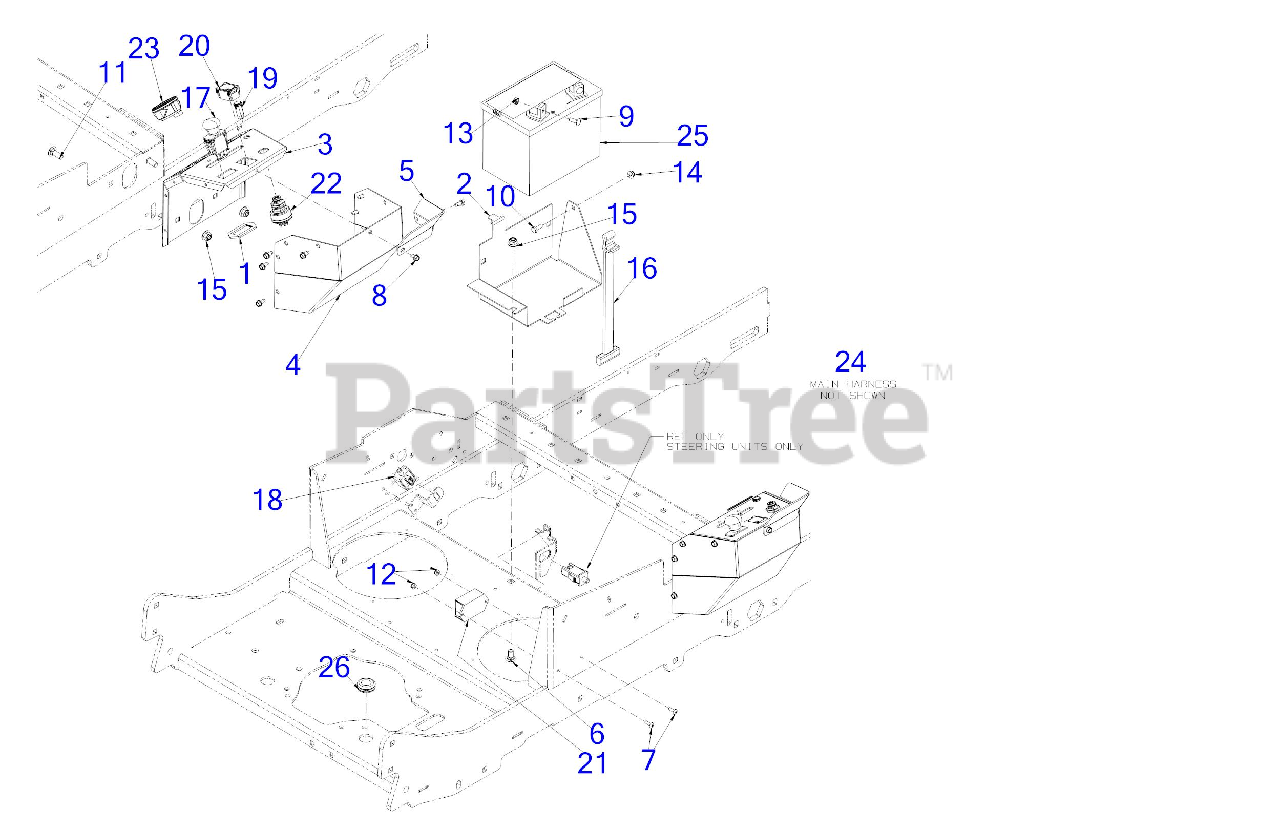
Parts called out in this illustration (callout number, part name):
1	BRACKET-PTO SWITCH
6	CARRIAGE BOLT 3/8-16 x .750 GR5
7	SCREW #10-24 x .62
8	SCREW 1/4-20 X.500
9	SCREW 1/4-20 x .75 GR5
10	SCREW 1/4-20X.75 GR5
11	CARRIAGE BOLT 3/8-16 x 1.00 GR5
13	SEMS NUT 1/4-20
14	FLANGE LOCK NUT
16	BATTERY RETAINER STRAP
17	PTO SWITCH (BLACK KNOB) TEXT SYM
18	3 POLE SWITCH ( NC-NO-NO)
19	INDICATOR LIGHT-RED
20	HOUR METER
21	CONTROL PANEL (SOFT CLUTCH)
22	KEY SWITCH (3 POSITION)
23	DUAL FUEL GAUGE
24	WIRE HARNESS
25	Purchase Battery Locally
26	RUBBER GROMMET
